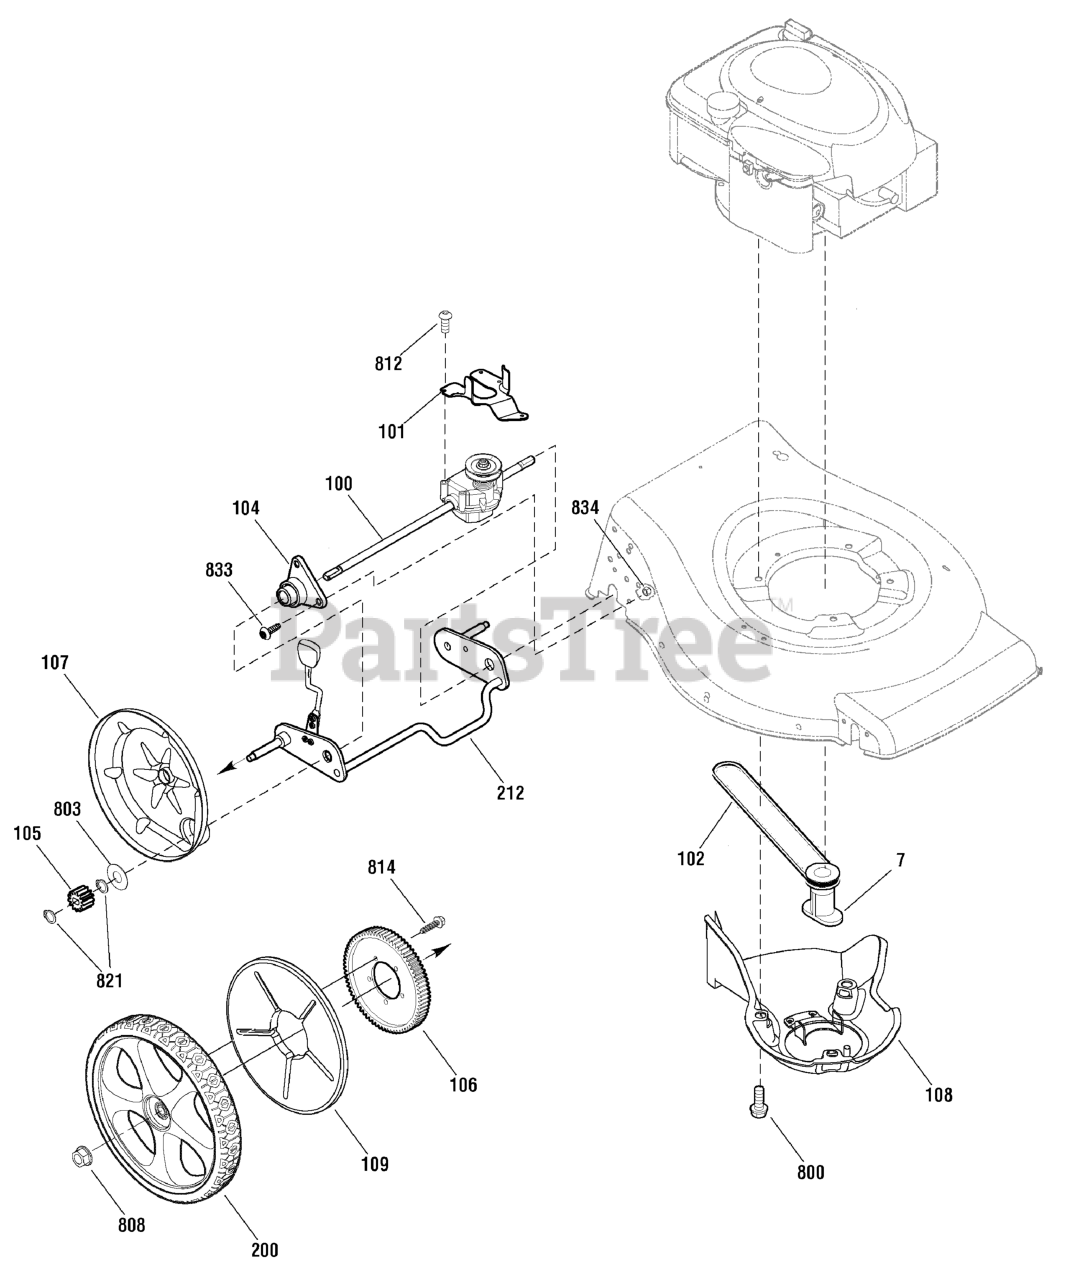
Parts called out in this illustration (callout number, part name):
7	BLADE ADAPTER ASSEMBLY
100	TRANSMISSION
101	BELT GUIDE, Transmission
104	SLEEVE ASSEMBLY, Rear Axle
105	GEAR, Pinion
106	GEAR, Drive
107	DUST COVER
108	BELT COVER ASSEMBLY
109	COVER, Wheel
200	WHEEL, Rear
212	CROSSBAR ASSEMBLY, Rear
800	SCREW, Hex Head, 3/8-16 x 1
803	WASHER, Thrust
808	NUT, Flange, 3/8-16
812	SCREW, #10 x 1
814	SCREW, 1/4-15 x 3/4
821	RING, External Retaining
833	SCREW, Torx, 1/4-20 x 5/8
834	NUT, Flange Lock, 1/4-20
